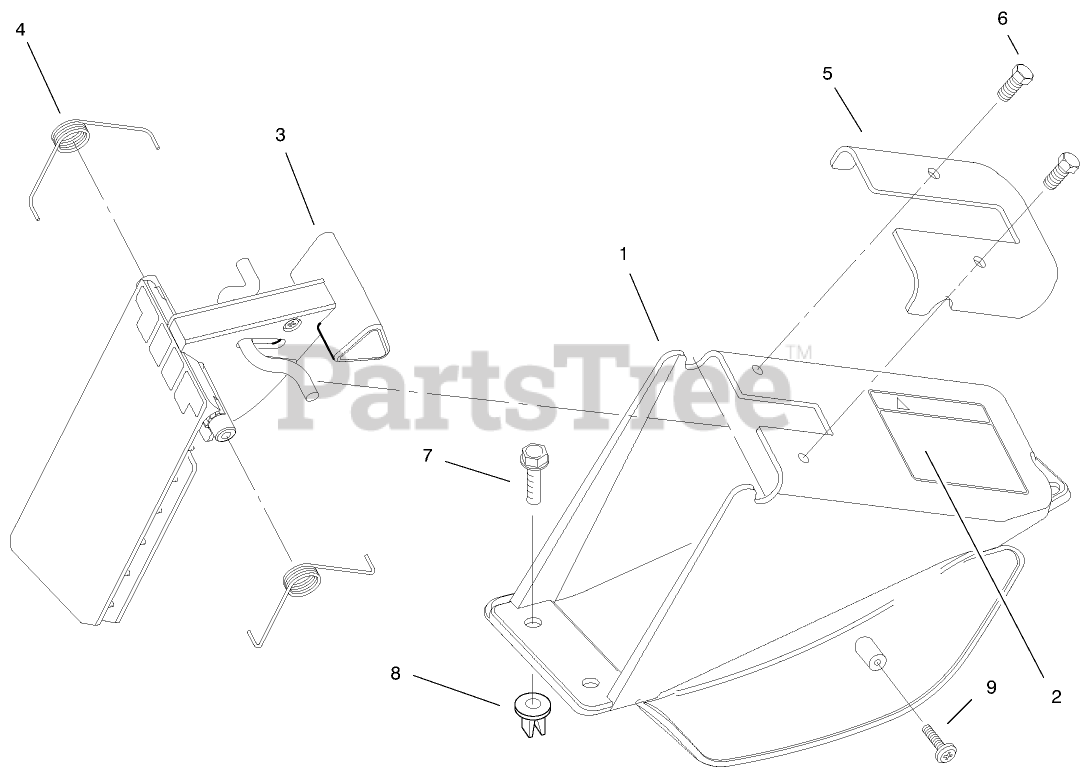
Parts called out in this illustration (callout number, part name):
1	CHUTE - DISCHARGE
2	DECAL - CAUTION DOOR
3	ASM - DISCHARGE DOOR
4	SPRING-DOOR, RH
5	Plate-Discharge
6	SCREW-PLASTITE
7	SCREW-HWH
8	NUT - CLIP
9	SCREW-PPH
